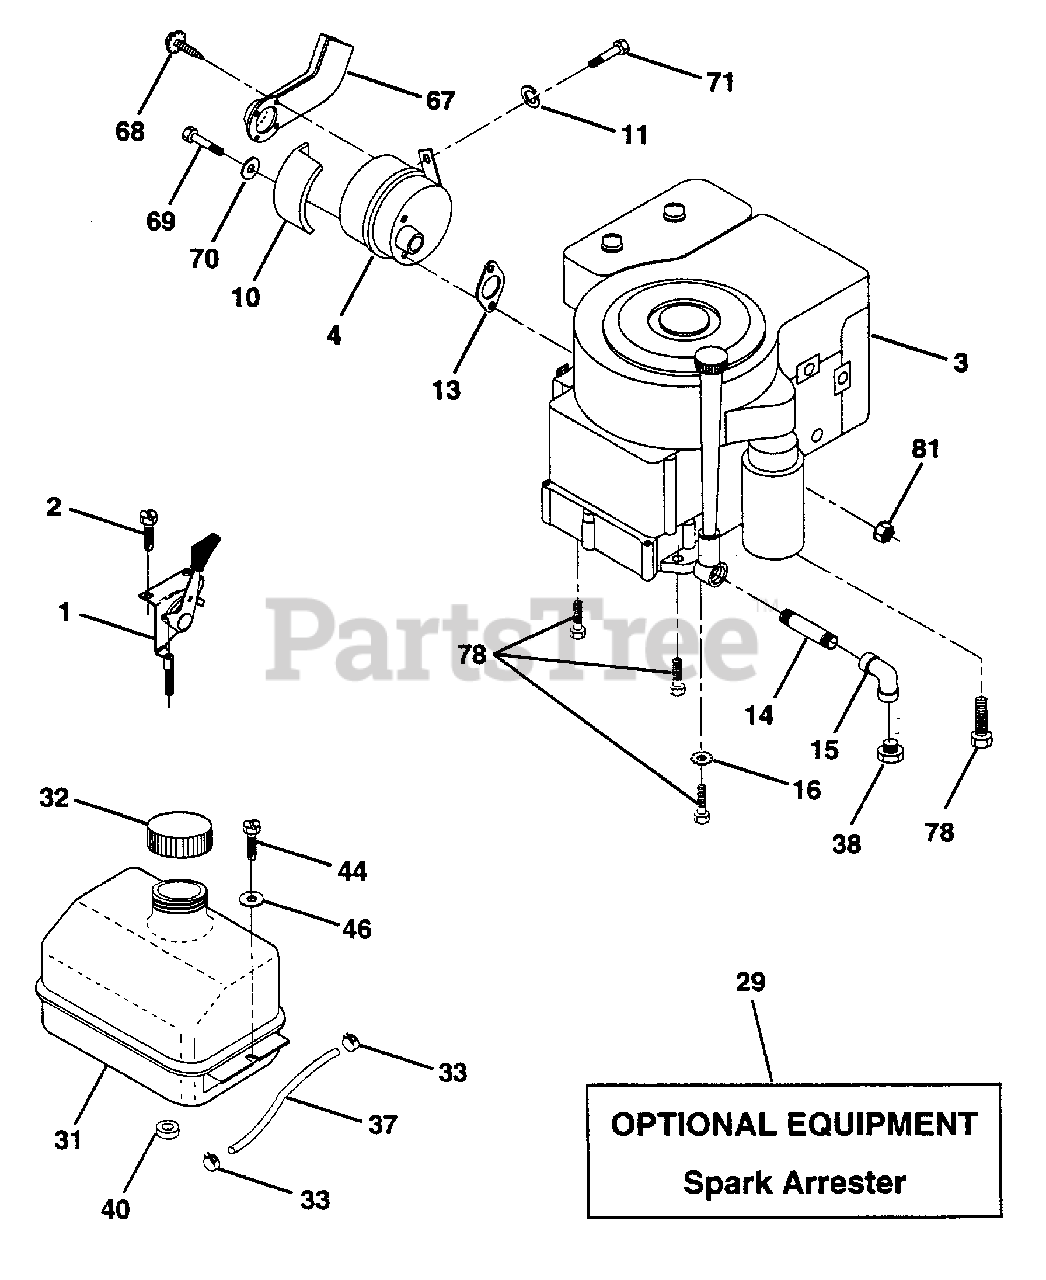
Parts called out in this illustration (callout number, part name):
1	THROTTLE CONTROL
2	SCREW LT
3	ENG B&S 10-12.5HP PWRBLT DC
4	MUFFLER LTV
10	SHIELD HEAT LTV
11	LOCKWASHER
14	PIPE NIPPLE
15	ELBOW
16	LOCKWASHER
31	TANK.FUEL.LT.
32	CAP ASM FUEL
33	HOSE CLAMP
37	LINE FUEL
44	SCREW HEX CRT
46	WASHER
67	DEFLECTOR MUFFLER
69	"BOLT,HEX"
70	WASHER T
71	BOLT HXHD FIN
78	SCREW
81	NUT
